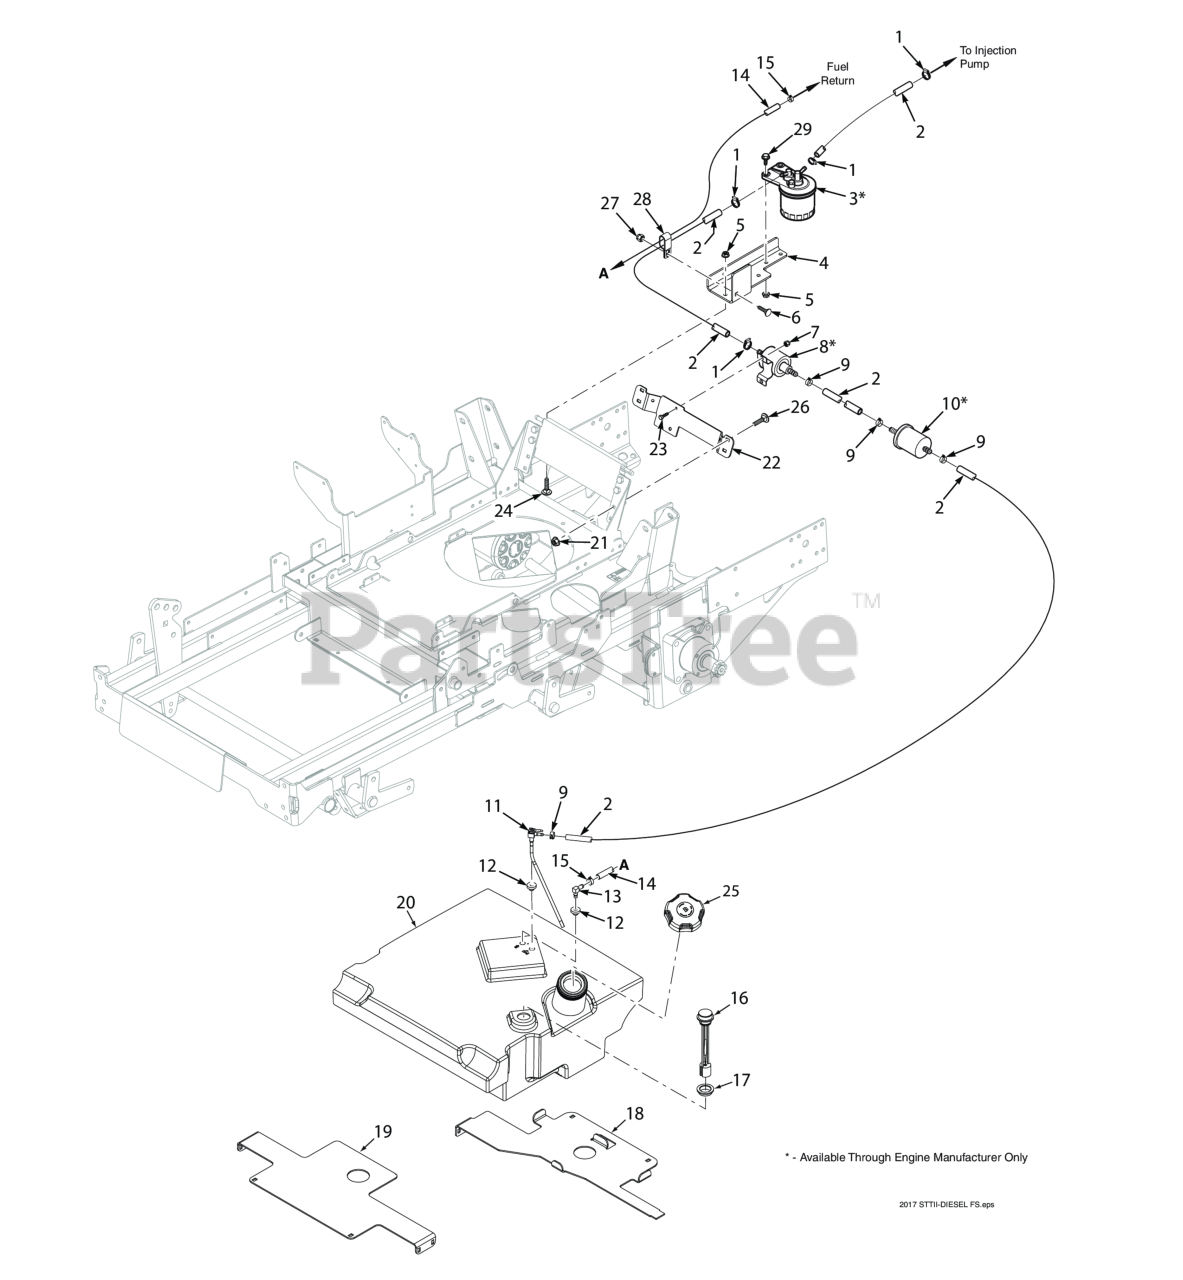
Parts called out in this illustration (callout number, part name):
1	Clamp, .69" Max. / .25" Min. Dia.
2	Fuel Hose, 5/16" I.D. Non-Perm (791DFI) - Order by Inch
3	Fuel Filter, Kubota
4	Bracket, Fuel Filter Mounting
5	Nut, Serrated Flange 5/16-18 (Right Front Engine Mounting, Briggs and Kohler Only)
6	Bolt, 5/16-18 x .75 RHSN Carriage
7	HEX, NUT, ELASTIC STOP LOCK, 1/4-20
8	Fuel Pump, Kubota
9	Clamp, Fuel Hose 5/16" I.D. (791DFI)
10	Fuel Pre-Filter, Kubota
11	Valve, Fuel Shutoff
12	Bushing, 0.56" Dia. Viton
13	Fitting, Return
14	Hose, 3/16" I.D. (order by inch)
15	Clamp, Fuel Return Hose
16	Fuel Guage Assy., 8"
17	Grommet, Fuel Gauge
18	Rear Support, Fuel Tank
19	Front Support, Fuel Tank
20	Fuel Tank Assembly (Incl. #11, 12, 15, 16)
21	NUT, 1/4-20 SERRATED FLANGE HEX HEAD
22	Mounting Bracket, Fuel Pump
23	Serr. Fl. Hex Head CPSCR, 1/4-20 x 3/4"
24	Bolt, Carriage 5/16-18x1" (large frame units only)
25	Cap, Fuel Tank
26	Serr. Fl. Hex Head CPSCR, 1/4-20 x 3/4"
27	Nut, Flange Head Elastic Stop 5/16-18
28	Clamp, Double Cable 5/8" ID.
29	Bolt, Heax Head 5/16-18 x 1" (48V / 52V)
